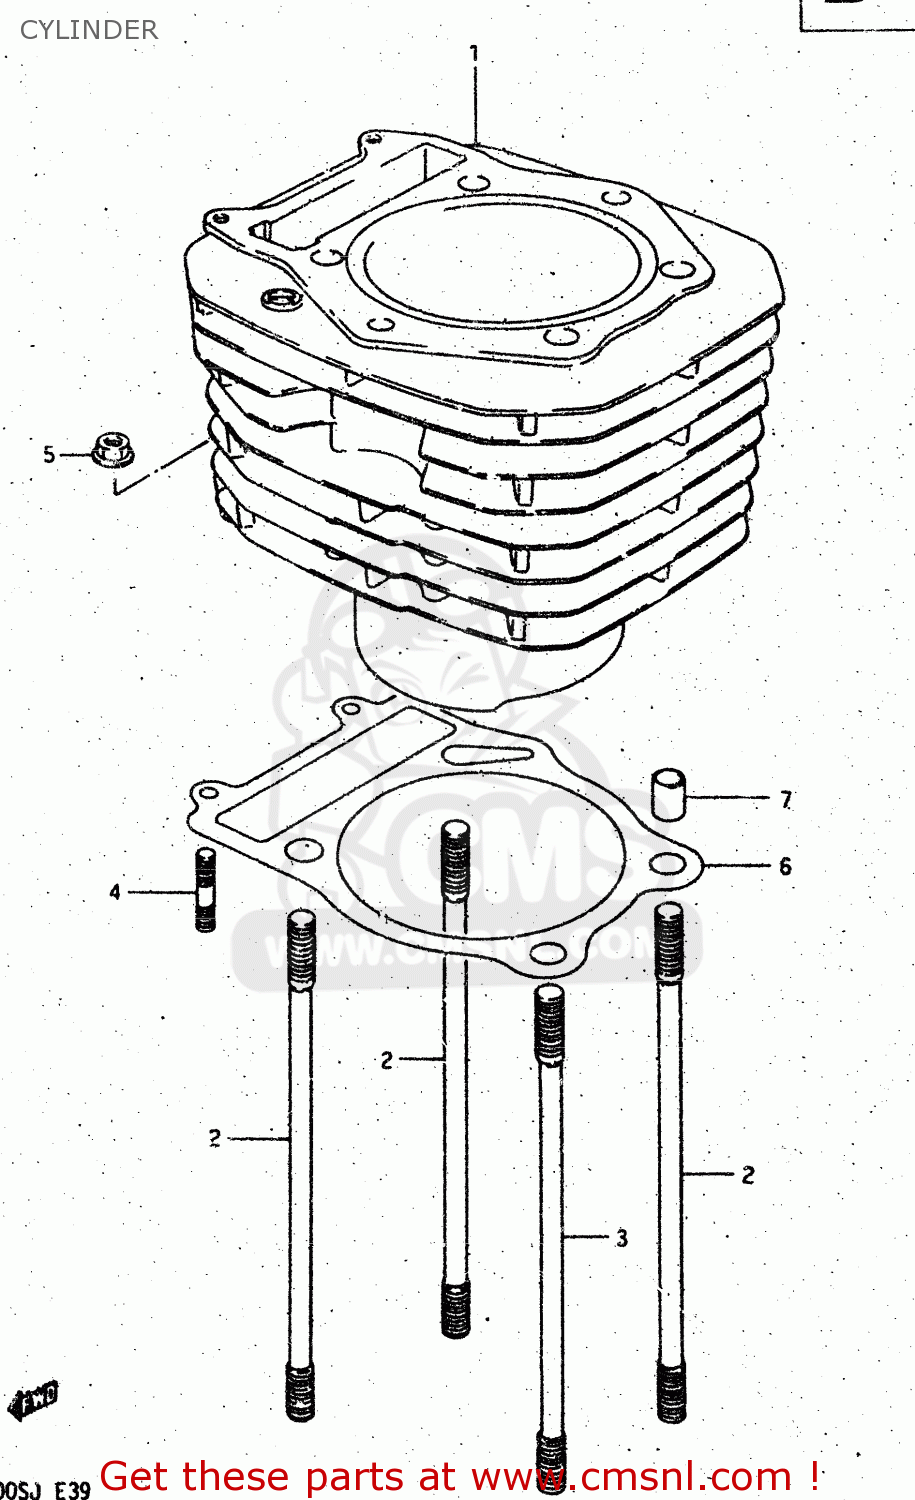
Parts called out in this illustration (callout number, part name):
1	CYLINDER
2	STUD
3	STUD
4	STUD BOLT L:20
5	NUT 6MM
6	GASKET,CYLINDER (MCA)
7	PIN
